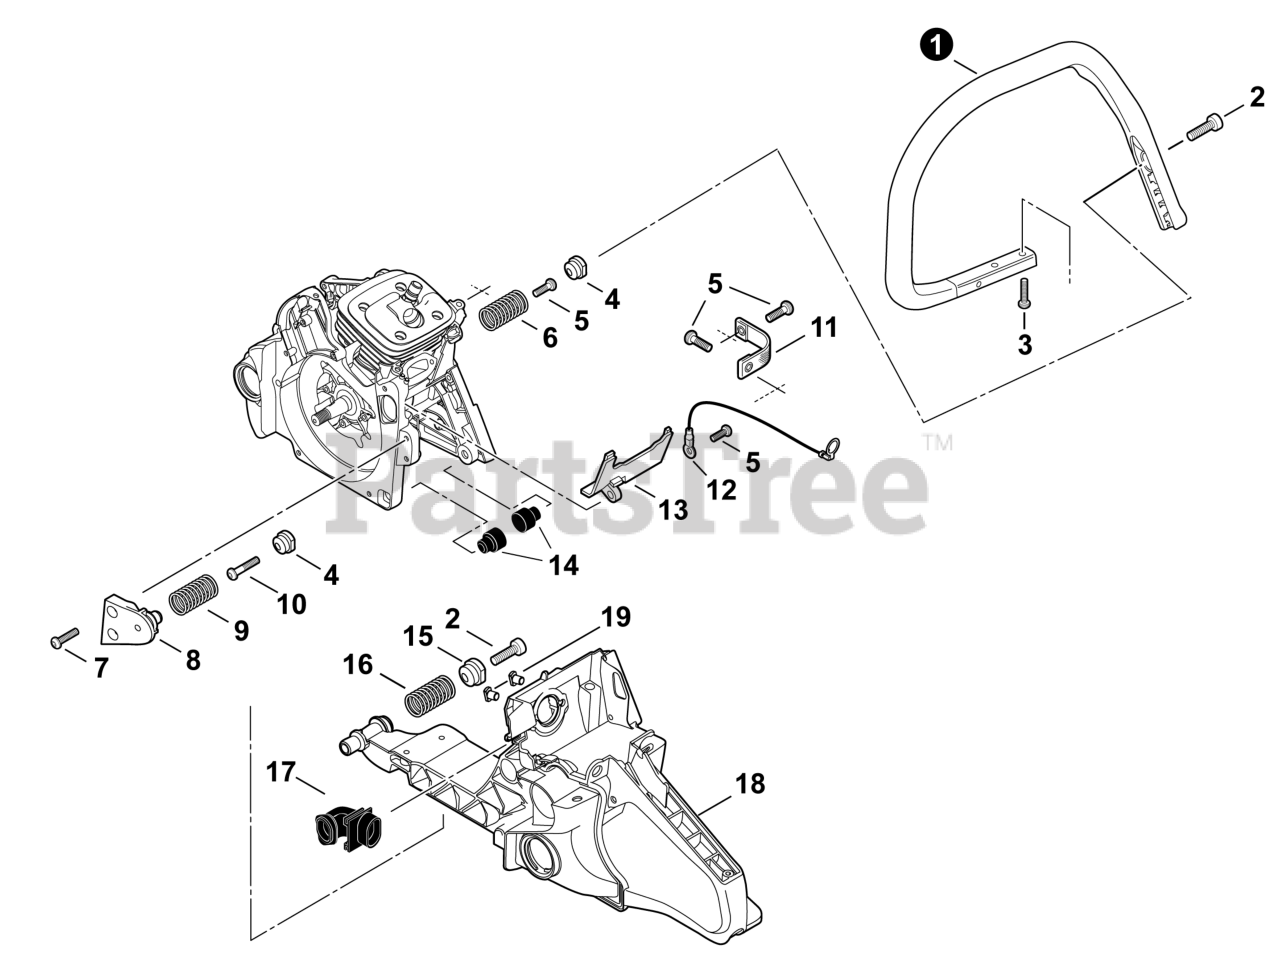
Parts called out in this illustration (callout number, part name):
1	HANDLE, FRONT
2	BOLT, TORX 6x20
3	BOLT, TORX 5x20
4	HOLDER, SPRING 14.4
5	BOLT, TORX 5x16
6	SPRING, COMPRESSION 17x38.4x2.6
7	BOLT, TORX 5x20
8	HOLDER, SPRING
9	SPRING, COMPRESSION 17x36.7x2.6
10	BOLT, TORX 5x25
11	STRAP, SAFETY
12	LEAD - GROUND L= 170
13	GUIDE, AIR
14	CUSHION
15	HOLDER, SPRING 17
16	SPRING, COMPRESSION 20x40x3.3
17	PIPE, AIR INTAKE
18	HANDLE, REAR
